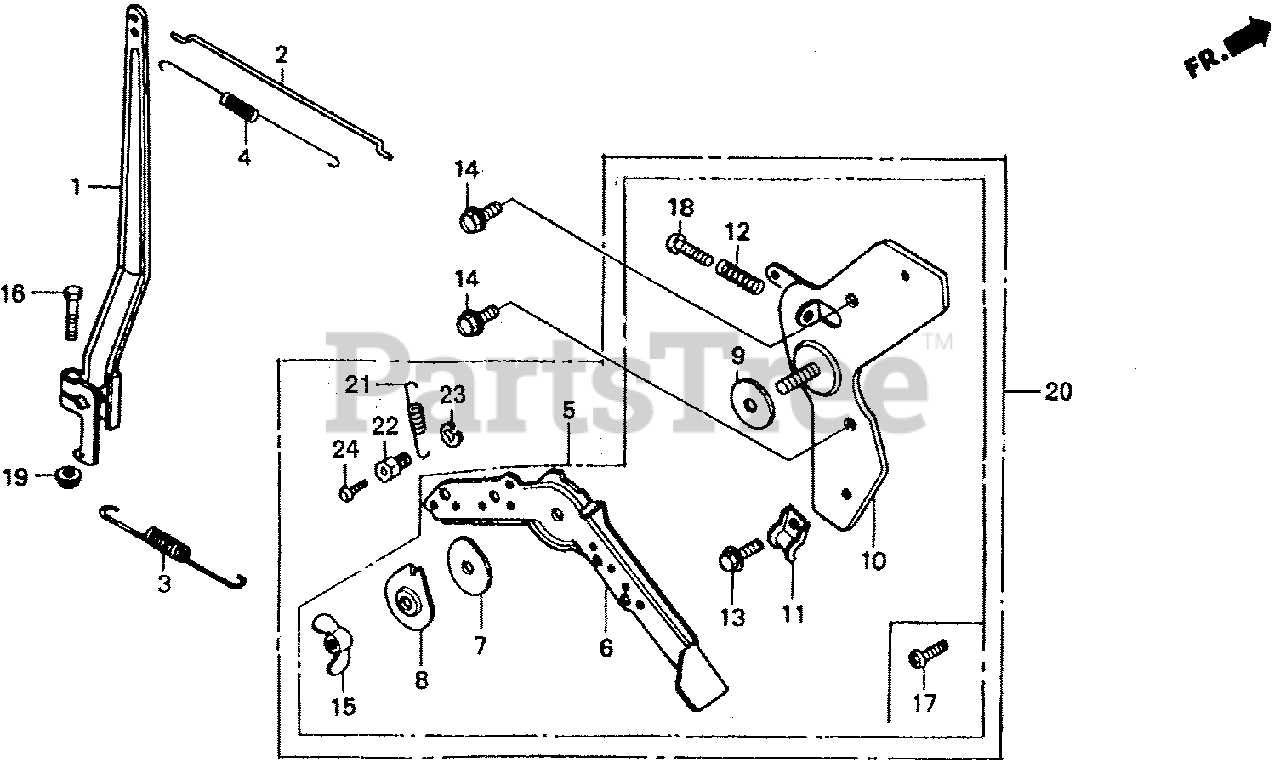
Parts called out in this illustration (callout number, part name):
1	ARM, GOVERNOR
2	ROD, GOVERNOR
3	SPRING, GOVERNOR
4	SPRING, THROTTLE RETURN
5	CONTROL ASSY.
6	LEVER, CONTROL
7	SPRING, LEVER
8	WASHER, CONTROL LEVER
9	SPACER, CONTROL LEVER
10	BASE, CONTROL LEVER
11	HOLDER, CONTROL CABLE
12	SPRING, CONTROL ADJUSTING
13	BOLT, FLANGE (5X10)
14	BOLT, FLANGE (6X12) (CT200)
15	WINGNUT (6MM)
16	BOLT, GOVERNOR ARM
17	SCREW, PAN (5X10)
18	SCREW, PAN (5X22)
19	NUT, FLANGE (6MM)
20	CONTROL ASSY.
21	SPRING, CABLE RETURN
22	HOLDER, WIRE
23	CIRCLIP (5MM)
